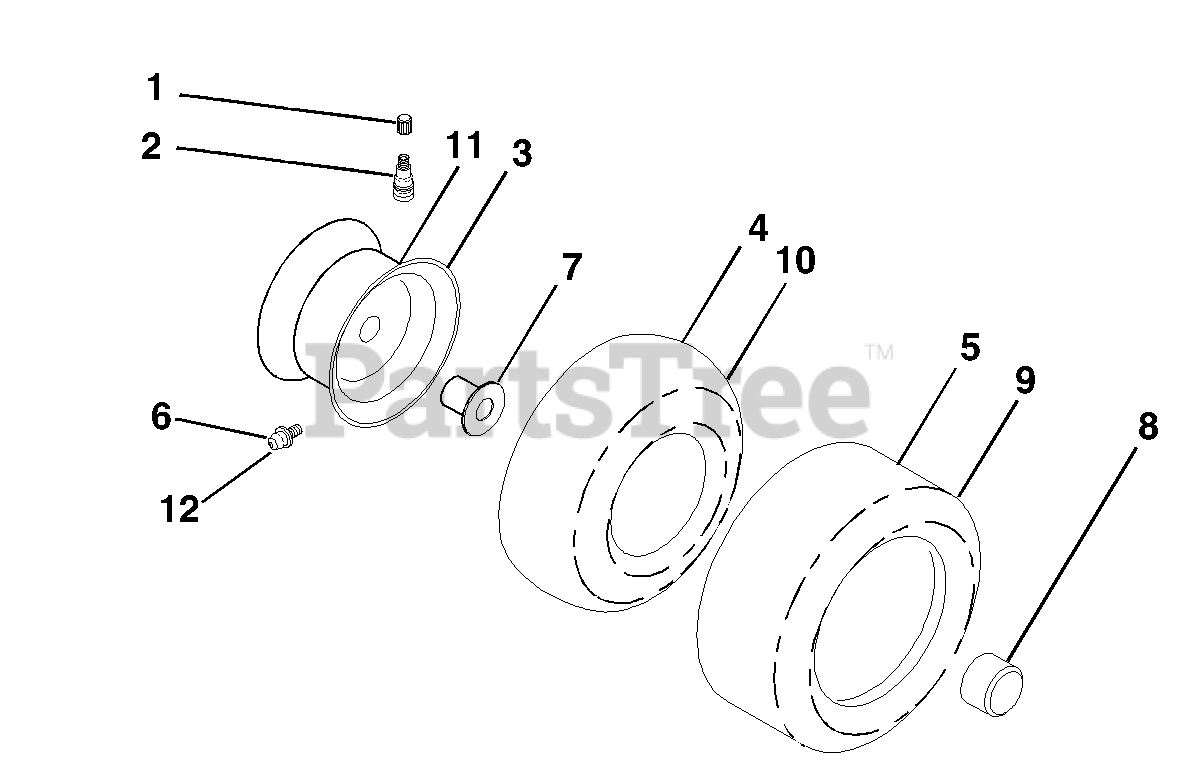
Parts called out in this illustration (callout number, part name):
1	Cap, Valve, Tire
2	Stem, Valve
3	Rim Assembly, Front
4	Tube, Front
5	Tire, Front
6	Fitting, Grease
7	Bearing, Flange
8	Cap, Axle
9	Tire, Rear
10	Tube, Rear
11	Rim Assembly, Rear
12	Fitting, Grease
